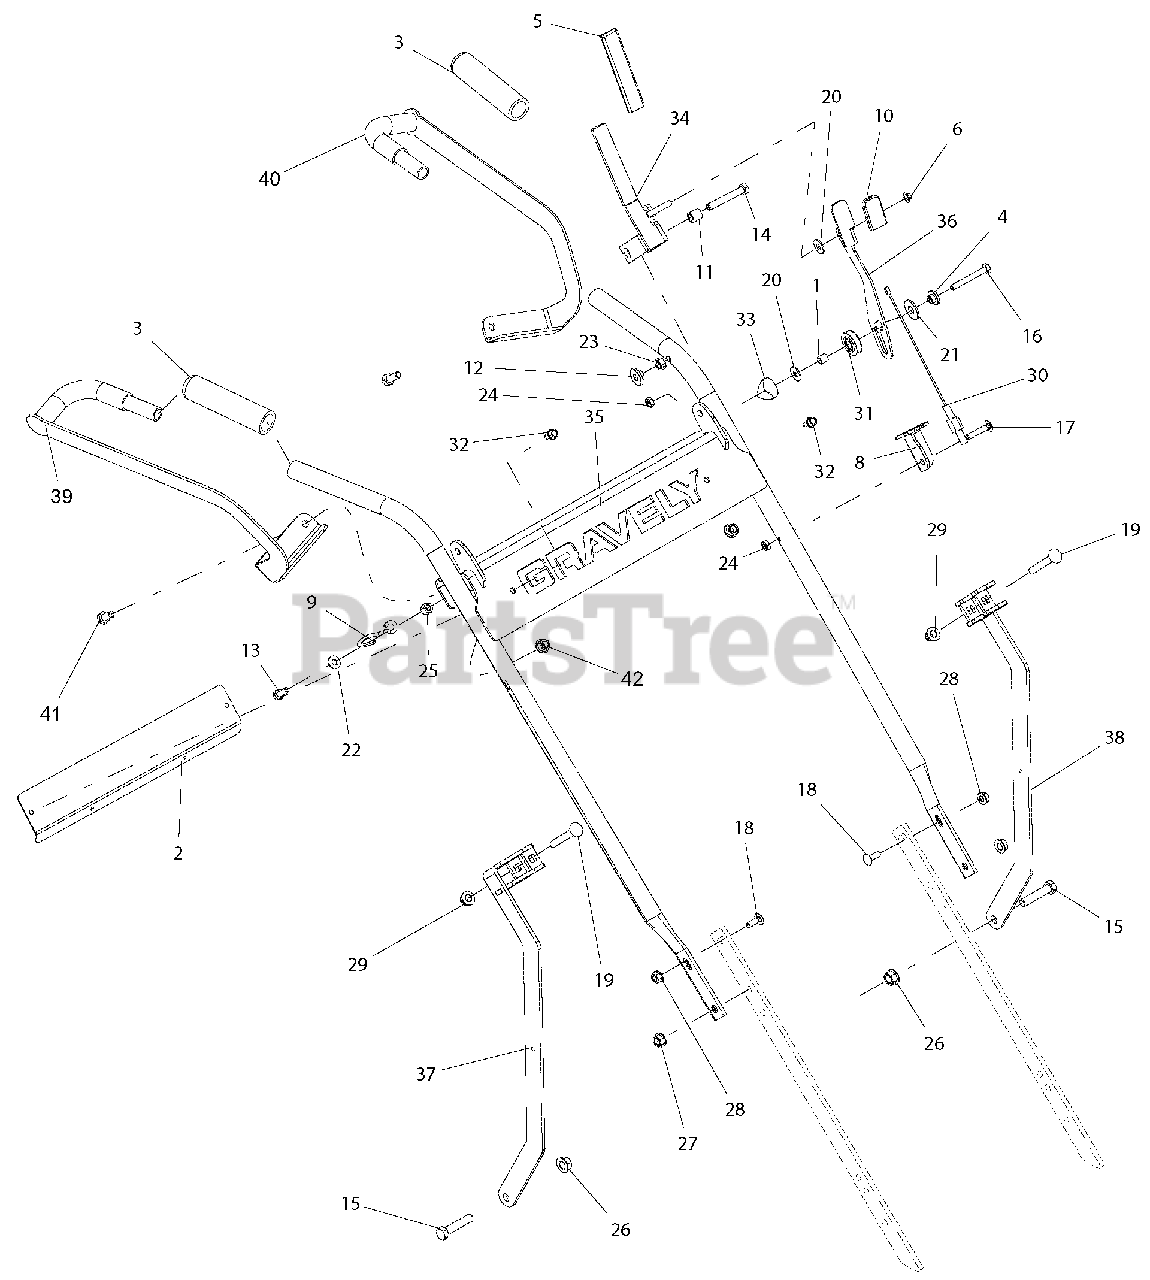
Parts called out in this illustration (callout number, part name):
1	TUBE, SPCR .280 X .375 X .375 REV
2	BACKER, GRAVELY
3	GRIP, BLACK 7/8ID
4	BSHG, FLG .266X.42X.150 PM
5	GRIP, MZR/MOMENT SP 7/8X3/4X4
6	PUSH, NUT .25
8	MOUNT, UPPER PTO CABLE (BLACK)
9	GUIDE, PULLCORD
10	GRIP, THUMB LATCH
11	BSHG-SLV .334X.500X.50
12	BSHG, FLG .32X.500.344X.880
13	BLT-HEX .25-20X.75 GR5 YWZC
14	BLT-HEX .31-18X2.00 GR5 YWZC
15	BLT-HEX .38-16X1.75 GR5 YWZC
16	BLT-HEX .25-20X2.00 GR5 YWZC
17	BLT-RDHDSQNK .25-20X1.25 G5 Y
18	BLT-RDHDSQNK .25-20X.75 G5 YWZC
19	BLT-RDHDSQNK .31-18X2.25 G5 Y
20	WSHR-FL-STL.312X.734X.065 YWZ
21	WSHR-FL-STL.438X1.00X.083 YWZC
22	WSHR-FL-STL.281X.62X.065 YWZC
23	NUT-LK-CTR .31-18 YWZC
24	NUT-JAM-NYL .250-20 W/INSERTYZ
25	NUT-LK-NYL .250-20 YWZC
26	NUT, LK-TOP-FLG .38-16 YWZC
27	NUT, LK-TOP-FLG .312-18 YWZC
28	NUT, LK-TOP-FLG .25-20 YWZC
29	NUT-LK-NYL-FLG .31-18 YWZC
30	CABLE, WAW PTO
31	PULLEY, CABLE
32	SCR-TAP .25-20X.50 HWH TR YWZ
33	SPCR, HANDLEBAR
34	WLDMT, PTO LEVER, HWM (BLACK)
35	WLDMT, HANDLEBAR HW MOWER (RED)
36	WLDMT, HWM PTO INTERLOCK
37	WLDMT, RH HANDLEBAR SUPPORT (RED)
38	WLDMT, LH HANDLEBAR SUPPORT (RED)
39	WLDMT, HWM HANDGUARD, RH (BLACK)
40	WLDMT, HWM HANDGUARD, LH (BLACK)
41	BLT-HEX .31-18X.75 GR5 YWZC
42	NUT, LK-TOP-FLG .312-18 YWZC
